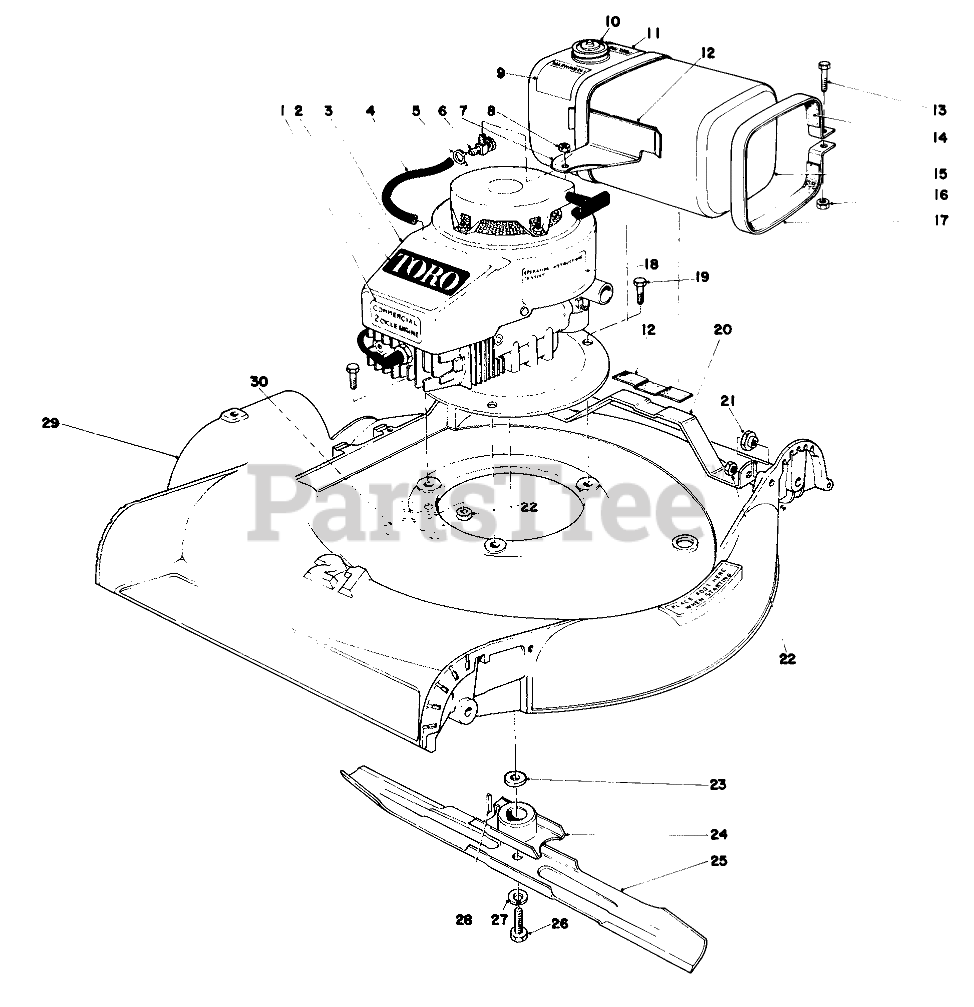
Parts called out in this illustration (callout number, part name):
1	DECAL COMM 2 CY ENG
2	Decal
3	Engine
4	GAS HOSE
5	Clamp
6	.125 ID SHUTOFF VALVE
7	Bracket Tank Mounting
8	Nut Recoil Mounting
9	DECAL WARNING
11	DECAL FUEL MIX
12	Felt Strip Tank Support
13	SCREW-HH
14	Felt Strip
15	Fuel Tank Assembly (Incl. Ref. #10)
16	NUT-LOCK, CONE
17	TANK STRAP
18	TORO DECAL
19	SCREW-HH
20	Tank Bracket
21	SPACER
22	NUT-LOCK, CONE
23	SPACER-BLADE RETAINER
24	BLD RETAINER W.A.
25	Blade
26	SPECIAL SCREW
27	WASHER-LOCK
28	KEY-SQUARE
29	Housing
30	Exhaust Baffle
